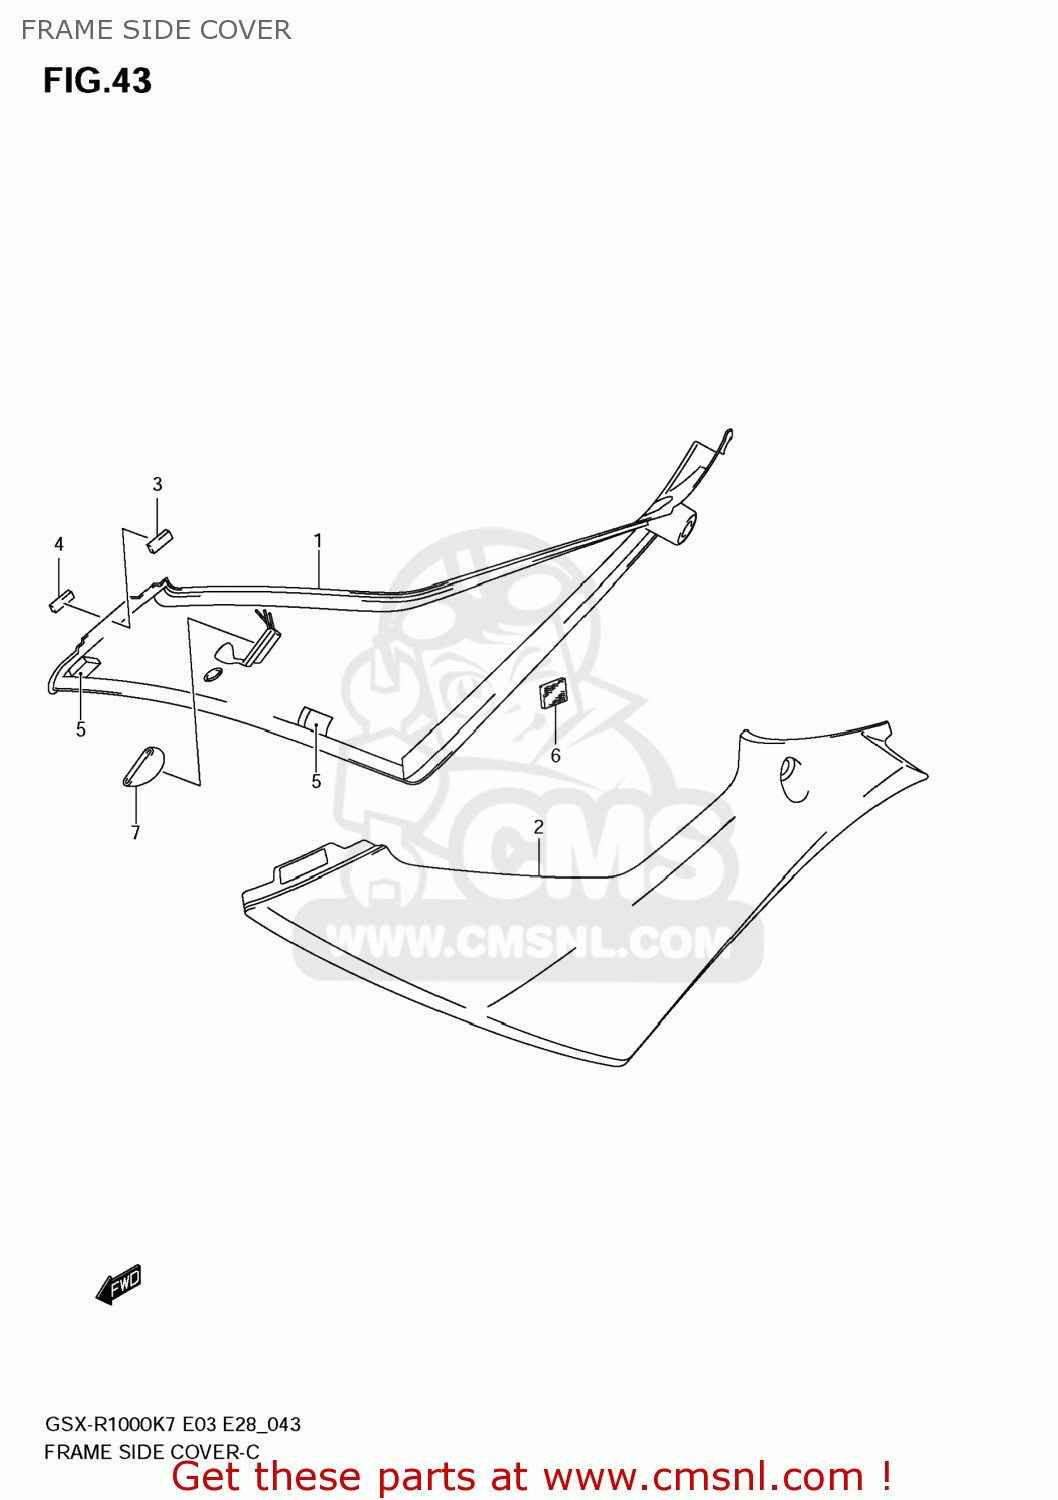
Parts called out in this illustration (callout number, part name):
1	COVER,FRAME SIDE,R(BLACK)
2	COVER,FRAME SIDE,L(BLACK)
3	CUSHION
4	PROTECTOR,FRAME COVER NO.2
5	PROTECTOR(50X50X5)
6	FASTENER
7	CUSHION
